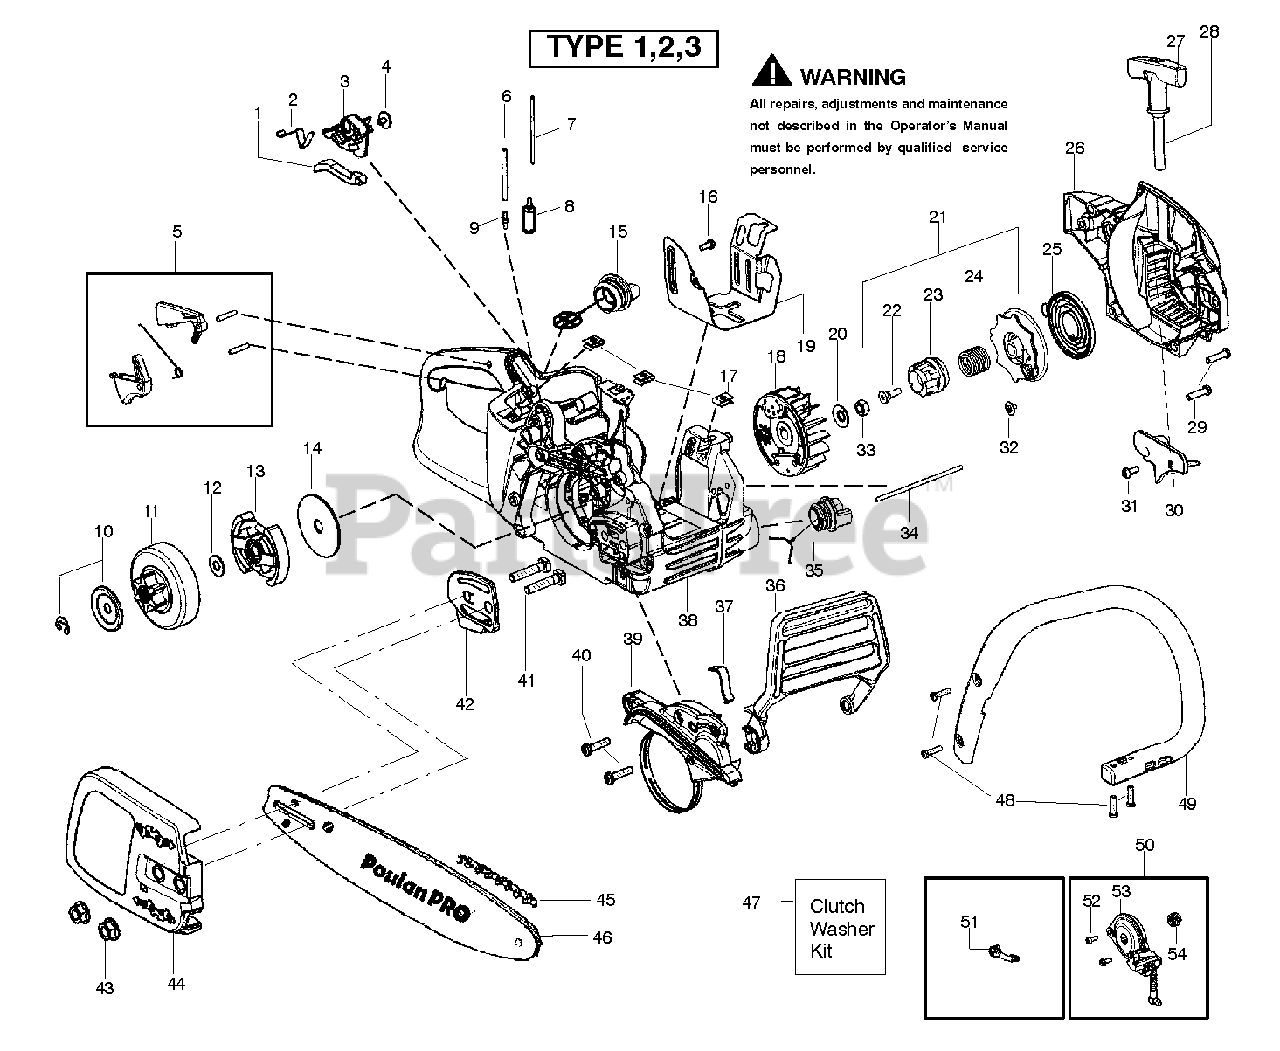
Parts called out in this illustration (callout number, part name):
1	KNOB CHOKE
2	SPRING IGNITION SWITCH
3	LEVER IGNITION SWITCH
5	KIT TRIG AND LOCKOUT
6	LINE KIT
7	KIT-LINE
8	FUEL PICK-UP ASSY
9	FUEL LINE FITTING
10	KIT SAS CLUTCH WASHER
11	ASSY CLUTCH DRUM 3/8
12	KIT SAS CLUTCH WASHER
13	ASSY CLUTCH
14	WASHER CLUTCH LARGE
15	FUEL CAP ASSY W/RET
18	FLYWHEEL ASSY WALBRO
19	SHIELD HEAT
20	WASHER-FLYWHEEL
21	KIT EPS STARTER
22	SCREW SHOULDER
23	HUB STARTER EPS
24	SPRING EPS
26	KIT FAN HSG PRO GOLD
27	HANDLE STARTER
28	KIT-ROPE
29	SCREW M5.38-14X22.225MM
30	BAFFLE FAN HOUSING
31	SCREW 6-19X.437
33	NUT-FLYWHEEL
34	ASSEMBLY-OIL-VENT
35	OIL TANK CAP
36	HANDGUARD
37	SPRING HANDGUARD
38	ASSY CHASSIS BLACK/GOLD EVAP
39	KIT CHAIN BRAKE
40	SCREW M5.38-14X22.225MM
42	PLATE BAR MOUNTING
44	HOUSING CLUTCH COVER(PRO GOLD)
45	ACCY PP CHN 18" 91VJ 62DL 3/8
46	ACC PP BAR 18"
47	KIT SAS CLUTCH WASHER
48	SCREW M5.38-14X22.225MM
49	HANDLE FRONT
50	KIT OIL PUMP
51	ASSY PICK UP OIL TANK
52	SCREW 6-19X.437
53	ASSY OIL PUMP
54	WORM GEAR
